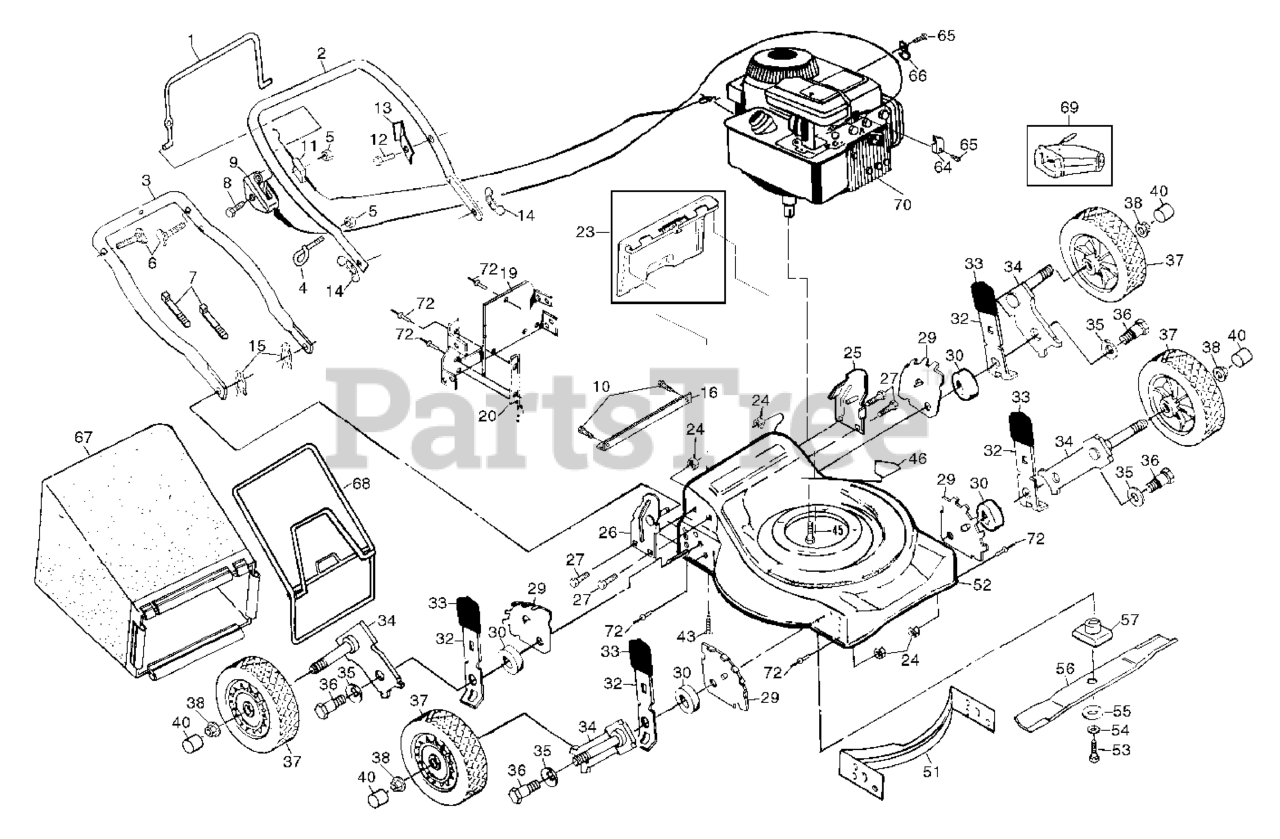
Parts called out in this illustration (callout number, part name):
1	CONTROL BAR
2	UPPER HANDLE
3	HANDLE.LOWER.STD.PNT.GREY
4	ROPE GUIDE
5	NUT
6	HANDLE BOLT
7	TIE GUIDE
8	SCREW 1/4-20 X 2.12
9	THROTTLE CONTROL
11	CABLE.MZR.51.RT.SP./PU.
12	TAPPING SCREW
13	BRACKET UPSTOP
14	NUT WING PM
15	HAIRPIN COTTER
16	REPL BY 532 14 61-43
20	SIDE BAFFLE
23	REAR DOOR ASSEMBLY KIT
24	LOCKNUT PM
25	HANDLE BRACKET ASSEMBLY - LEFT
26	HANDLE BRACKET ASSEMBLY-RIGHT
27	SELF-TAPPING SCREW 5/16-18X3/4
29	WHEEL ADJUST BRACKET
30	RP SPACER HT ADJ
32	SELECTOR SPRING
34	AXLE, REAR
35	WASHER.BELLEVILLE (3 2 LB)
36	BOLT
37	Wheel & Tire Assembly 7.0 x 1-1/2
38	HEX FLANGE LOCKNT
45	BOLT 3/8-16X1-1/8
46	DECAL MOWER CUT/FINGER
53	SCREW, HEX HD 3/8-24 X 1-3/8
54	LOCKWASHER
55	WASHER,HARDEN
57	BLADE ADAPTOR
64	WASHER
65	SCREW.HEX.HEAD.WASHER.10-16
66	GUIDE CLIP PM
68	CATCHER.FRAME.WALK
72	RIVET BLIND
